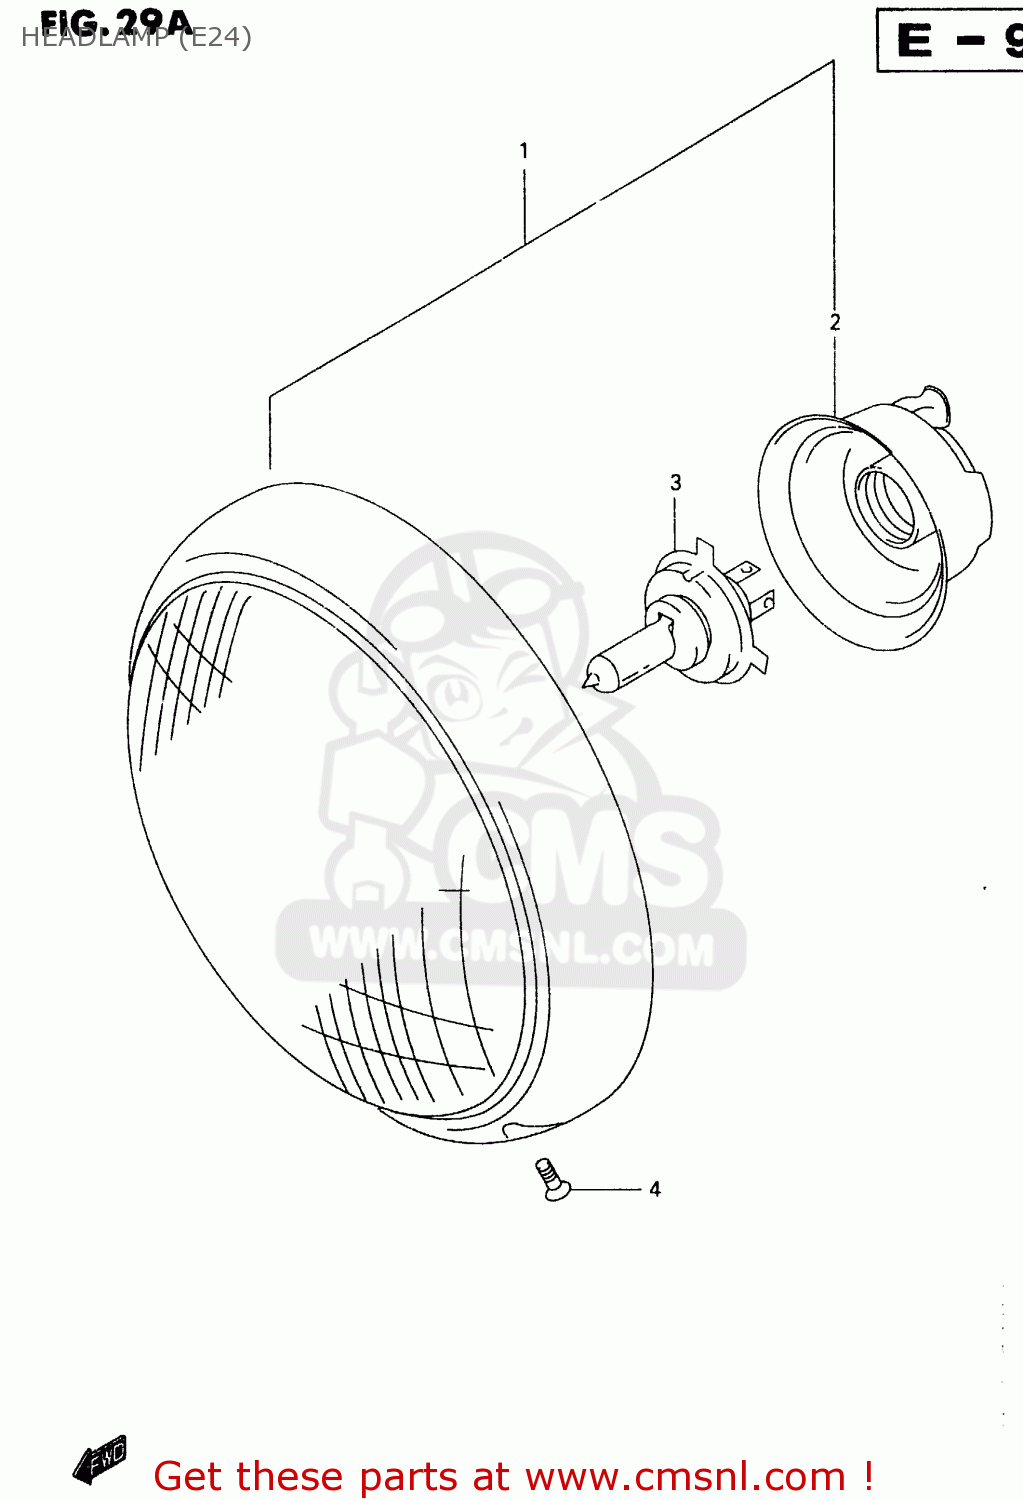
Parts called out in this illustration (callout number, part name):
1	HEADLAMP ASSY
2	COVER,SOCKET
3	BULB(12V60/55W,H4)
4	SCREW(5X12)
